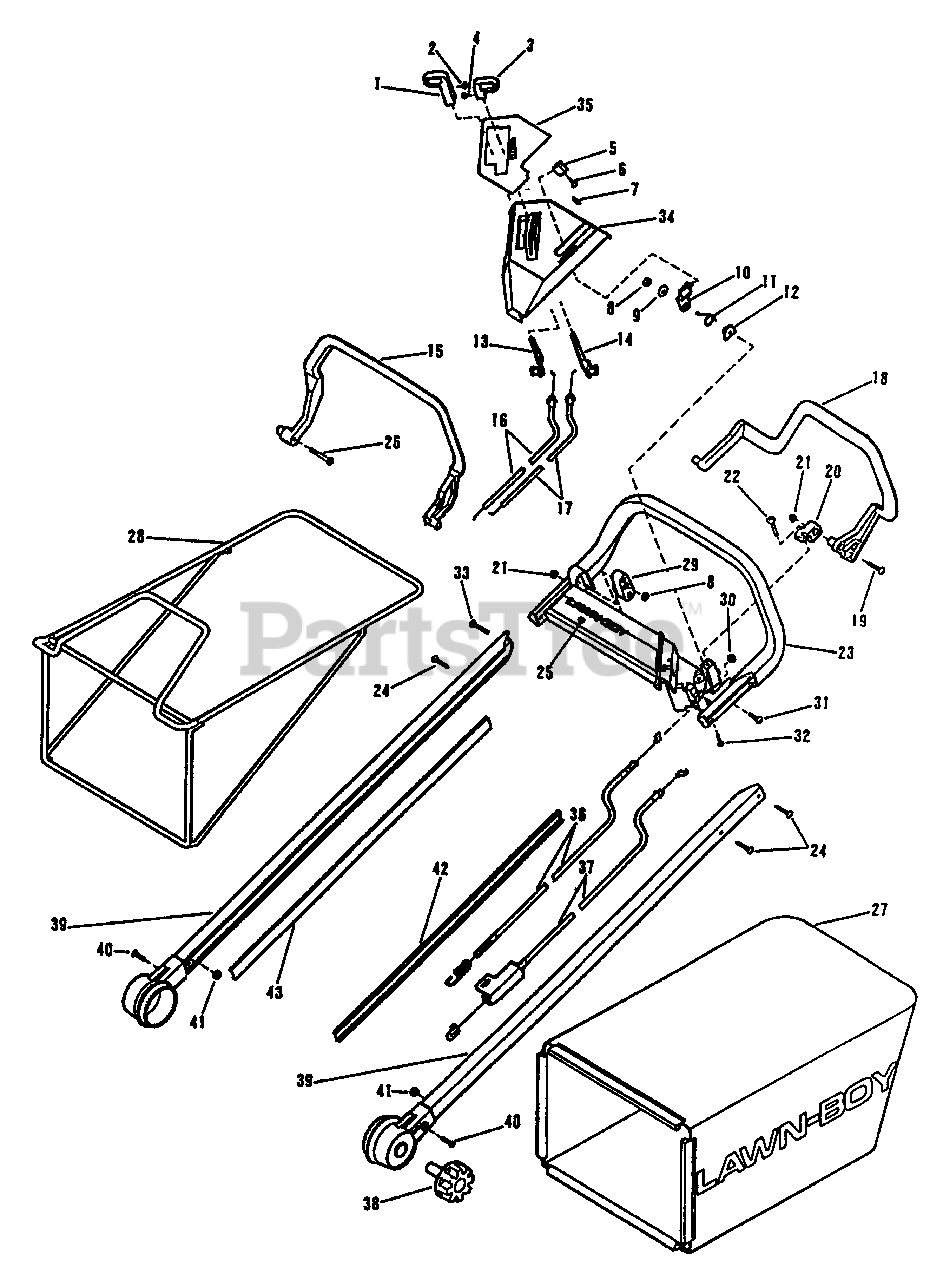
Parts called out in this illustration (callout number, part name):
1	Knob Assembly-Gear Select
2	Set Screw
3	Knob Assembly-Throttle
4	Set Screw
5	Knob Assembly-BBC Latch
6	Set Screw
7	Plug
8	Nut
9	Washer
10	BBC Latch Lever
11	Spring
12	Spacer
13	Gear Select Lever
14	Throttle Lever
15	Blade Brake Bail
16	Cable Assembly-Gear Select
17	Cable Assembly-Throttle
18	Self-propelled Bail
19	Screw
20	Bail Pivot
21	Nut
22	Screw
23	Handle and Decal Assembly
24	Screw-Thread Forming
25	Decal-Lawn-Boy
26	Screw
27	Rear Grass Bag
28	Frame
29	Bail Block
30	Nut-Self-propelled Cable
31	Screw
32	Screw
33	Screw
34	Upper Cover Assy (BMRB)
35	Plate
36	Cable Assembly-Self-propelled
37	Cable Assembly-BBC
38	Knob-Handle Mounting
39	Handle Knuckle and Extrusion
40	Screw
41	Nut
42	Handle Insert-Cable Side
43	Handle Insert
